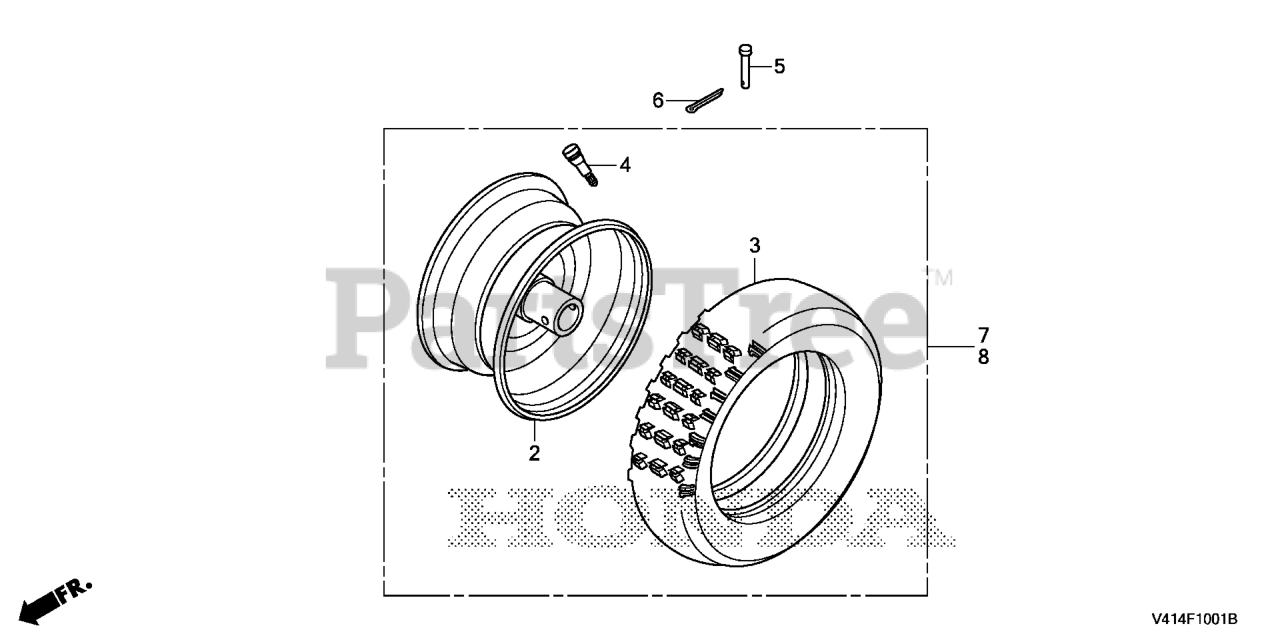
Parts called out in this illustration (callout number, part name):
3	TIRE,15X5.00-6
4	VALVE, RIM
5	PIN, CLEVIS (6.3X35)
6	PIN, COTTER (3.0X18)
7	WHEEL ASSY., R. (15X5.00-6)
8	WHEEL ASSY., L. (15X5.00-6)
